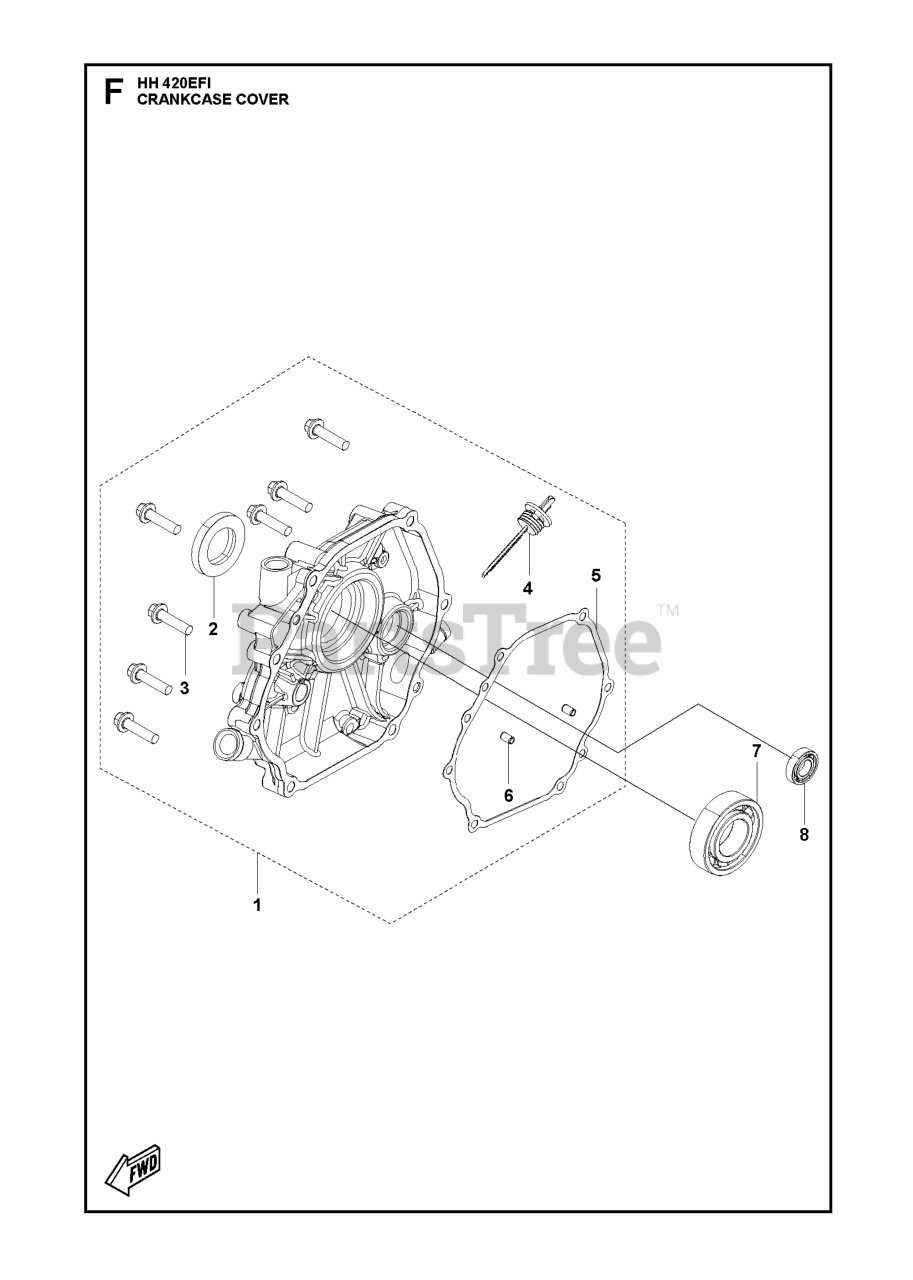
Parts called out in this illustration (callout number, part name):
1	COVER KIT CRANKCASE COVER
2	SEAL OIL SEAL
3	BOLT
5	GASKET CRANKCASE COVER GASKET
6	PIN LOCATION PIN
7	BALL BEARING
8	BALL BEARING
